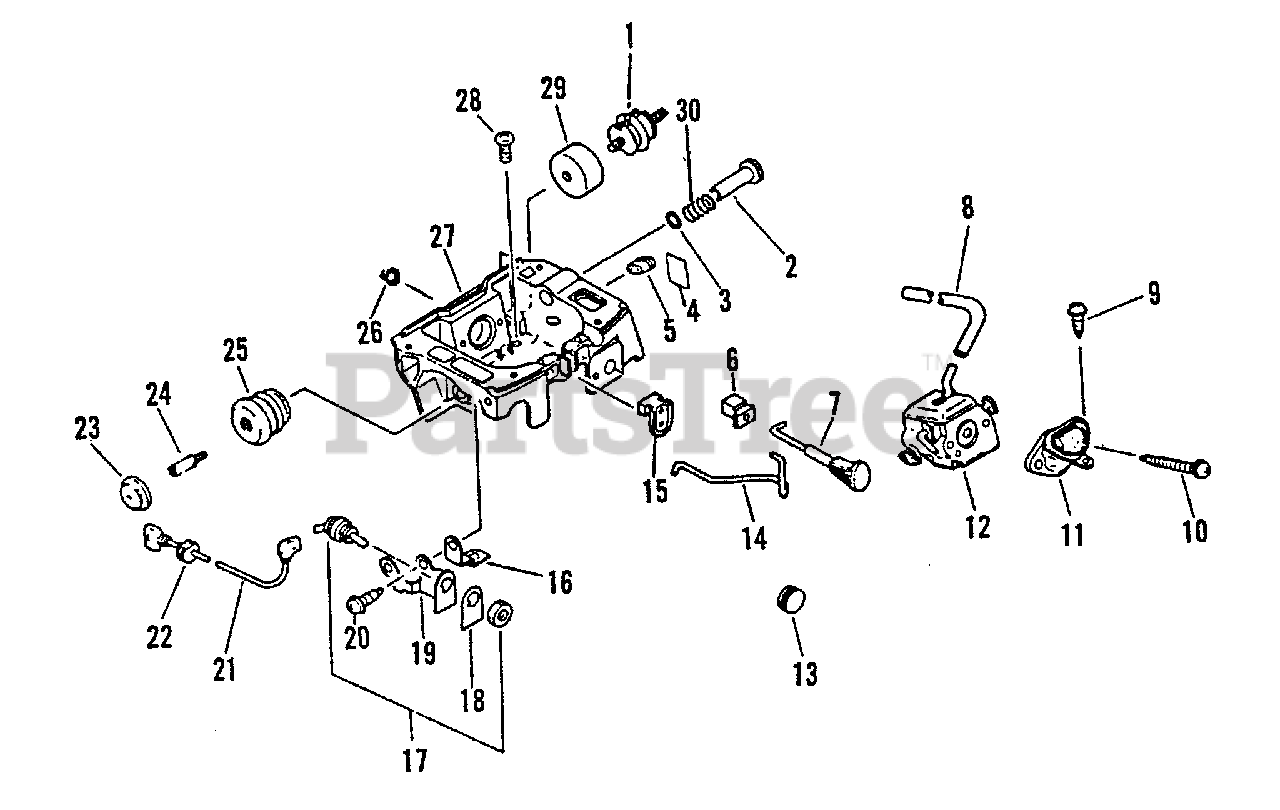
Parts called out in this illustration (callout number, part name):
1	CUSHION
3	O-RING 6 MM
4	LABEL, CAUTION - IDLE
6	GROMMET
7	ROD, CHOKE
8	PIPE, IMPULSE
9	SCREW 5×14
10	BOLT 5×55
11	GASKET
12	CARBURETOR
14	ROD, THROTTLE
15	GUIDE, THROTTLE ROD
16	PLATE - GROUND
17	SWITCH, ON-OFF
18	LABEL - SWITCH
19	BRACKET, SWITCH
20	SCREW 5×10
21	LEAD - GROUND
23	CAP, CUSHION
25	CUSHION
27	CASE, CARBURETOR
28	SCREW 5×20
29	PLATE, CUSHION
